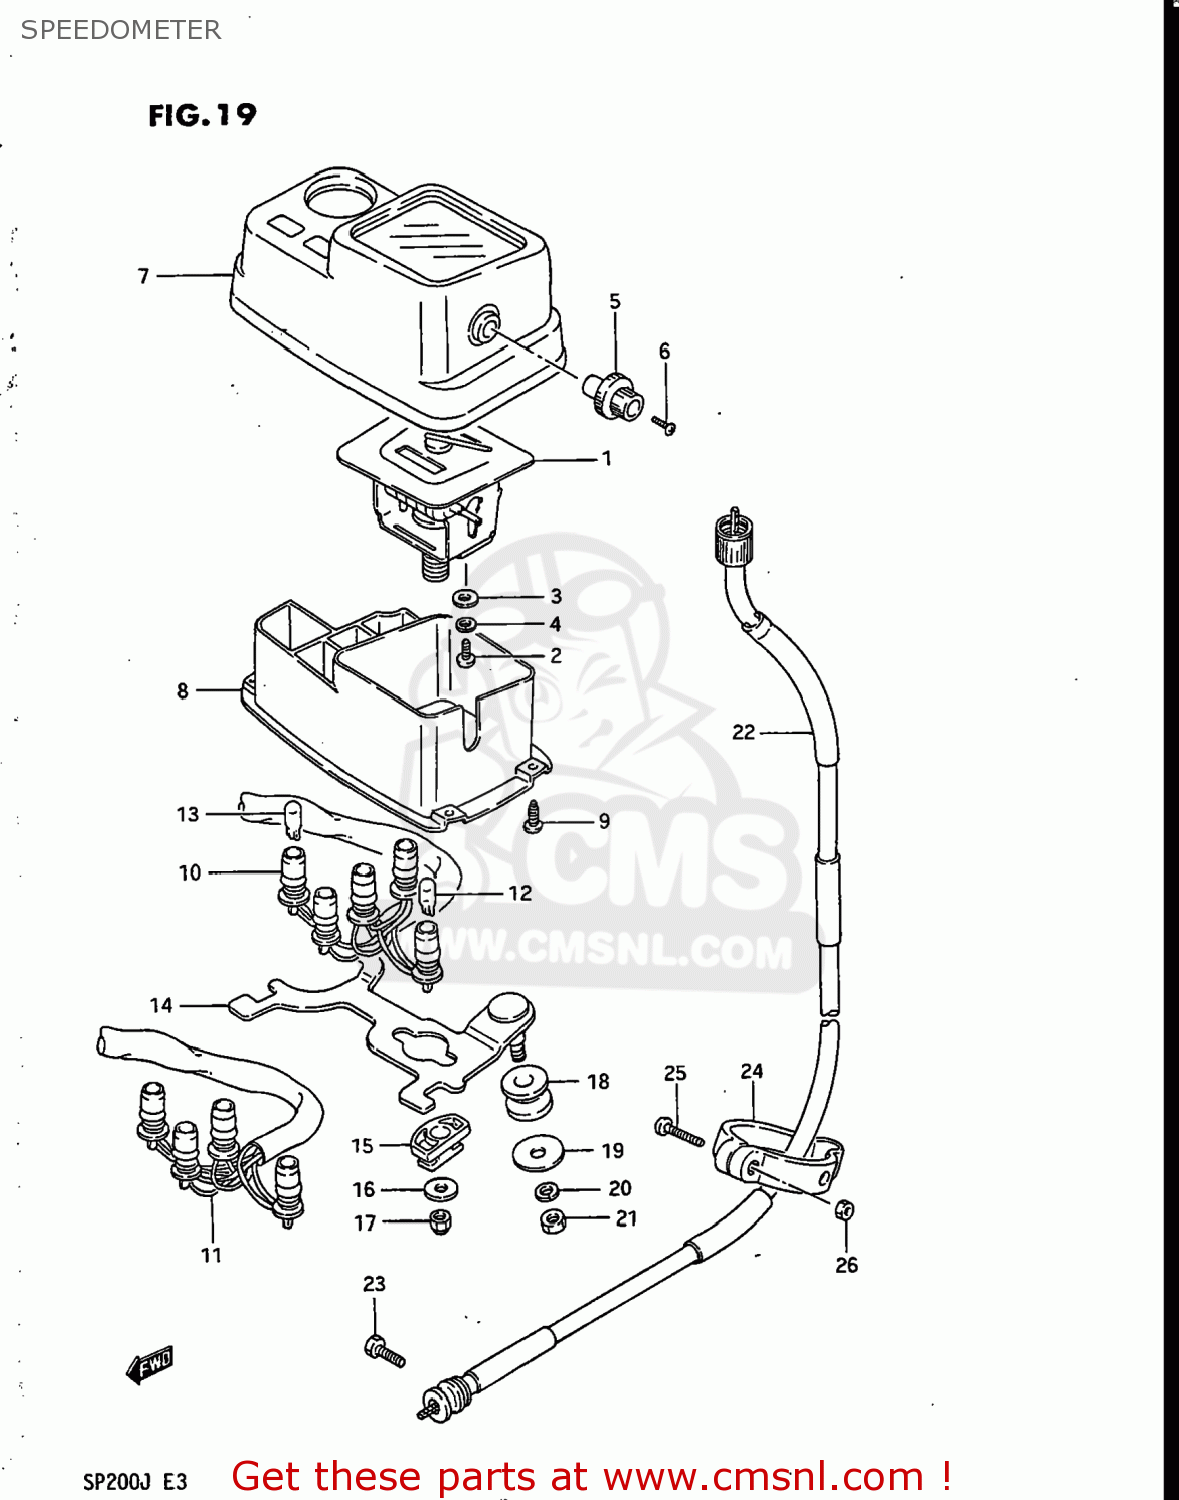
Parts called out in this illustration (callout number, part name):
1	SPEEDOMETER
2	SCREW
3	WASHER
4	LOCK WASHER
5	KNOB,TRIP
6	ROTOR,SPEED
7	HOOD,METER
8	CASE,METER
9	SCREW
10	SOCKET,METER
11	SOCKET,METER
12	BULB(12V3.4W,T10)
13	BULB(12V1.7W,T10,WB121)
14	BRACKET,METER
15	CUSHION
16	WASHER
17	NUT
18	CUSHION
19	WASHER
20	WASHER,LOCK
21	NUT
22	CABLE ASSEMBLY,SPEEDOMETER
23	BOLT
24	CLAMP,SPEEDOMETER CABLE
25	SCREW
26	NUT ,5MM
